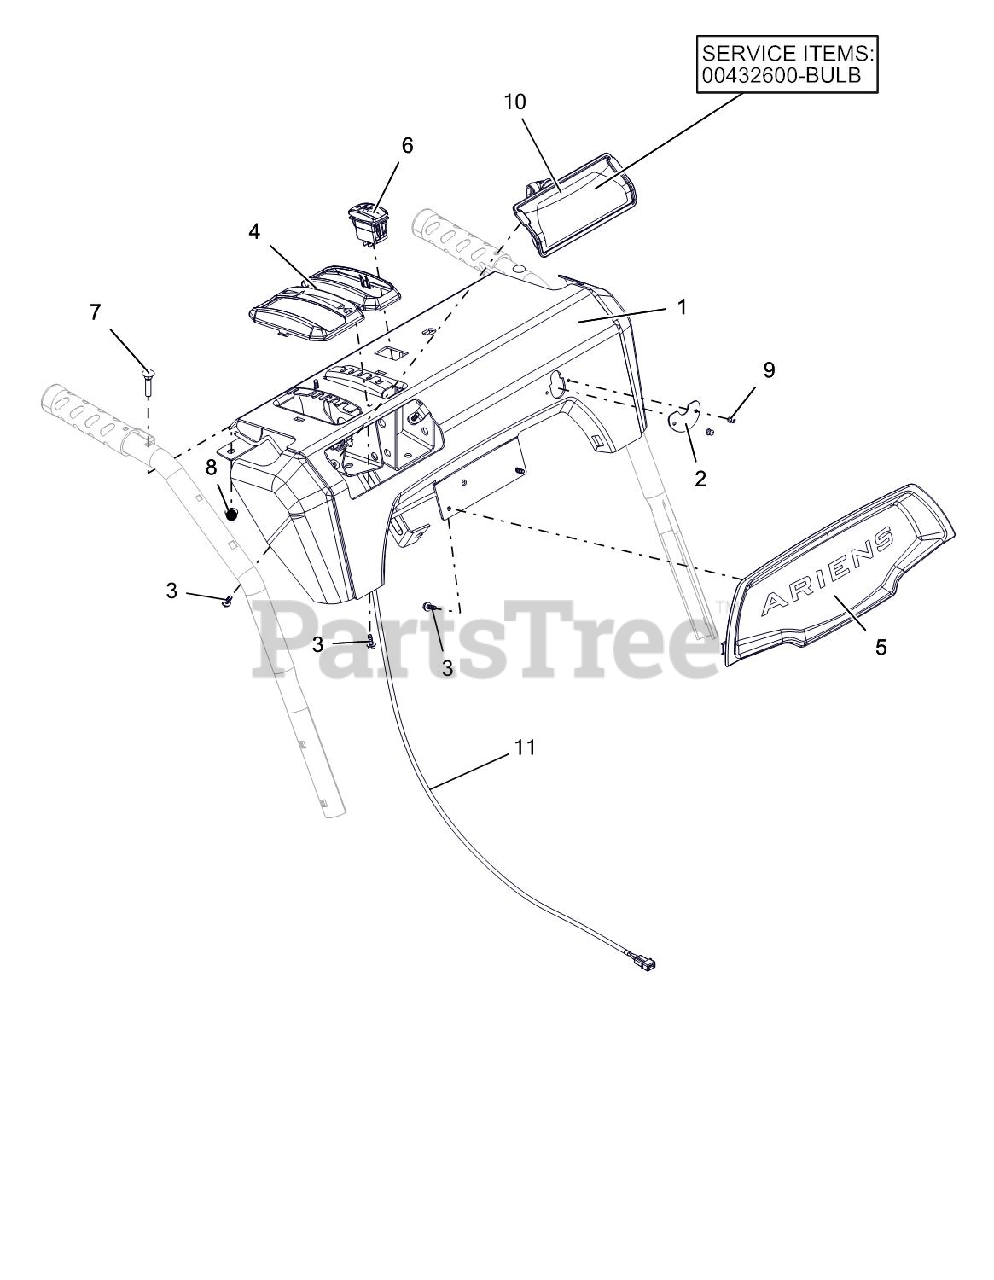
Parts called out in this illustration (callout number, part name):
1	CONTROL PANEL W/DECAL FRIC-ID
2	COVER, DASH BRKT, ID
3	SCR-TAP #10X.50 BOSS INDHXHD
4	BEZEL, SHIFT - FRICTION SNOW
5	BEZEL, DASH - ARIENS LG DASH
6	SWITCH,ROCKER SPST-ON/OFF
7	BLT-RDHDXLSQNK.25-20X1.25 G5ZC
8	@NUT-LK-CTR-FLG .25-20 YWZC
9	RVT-POP #43 .125X.313 STL ZINC
10	BULB, LIGHT-HALOGEN 20W
10	HEADLIGHT ASY, HALO 20W 2SHOT
11	HARNESS, LIGHT & WARMER
